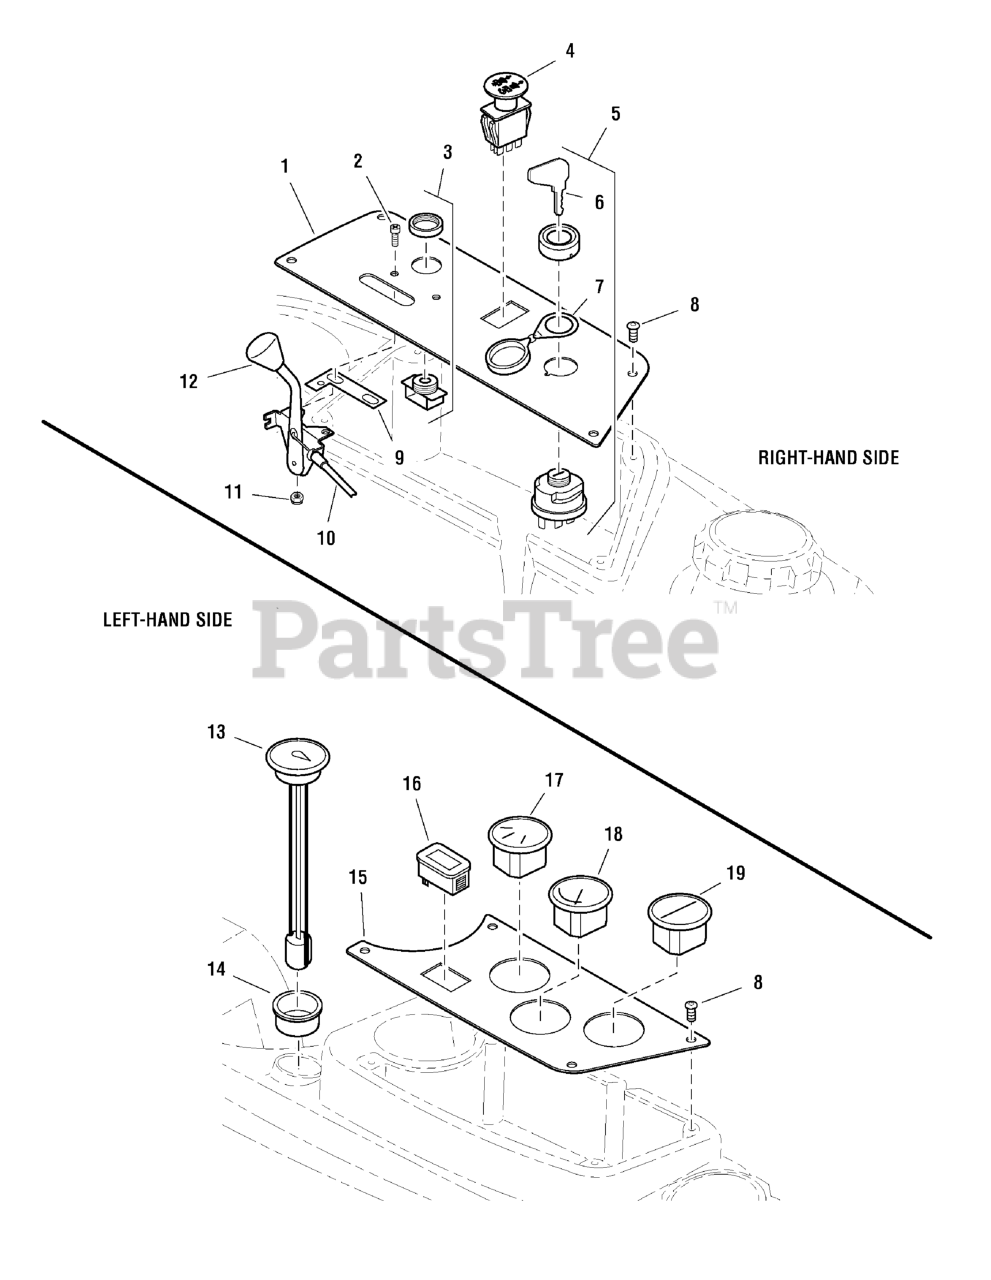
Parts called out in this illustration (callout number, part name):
1	CONTROL PANEL-RH
2	SCREW, #10-24 x 3/4
3	INDICATOR, Glow Plug
4	SWITCH, BLADE ENGAGEMENT
5	SWITCH, Ignition, Complete
6	KEY, Ignition
7	COVER PLATE
8	SCREW, Allen Head, 1/4-20 x 1/2
9	THROTTLE STOP PLATE
10	CABLE, Throttle Control, 47-1/2"
11	NUT, #10-24 Hex Nylon Lock
12	HANDLE, THROTTLE CONTROL
12	THROTTLE CONTROL HANDLE/KNOB
13	GAUGE, FUEL, 12
14	GROMMET
15	CONTROL PANEL-RH
16	HOUR METER
17	GAUGE, Voltmeter
18	GAUGE, Water Temperature
19	GAUGE, Warning, Oil/Temp
